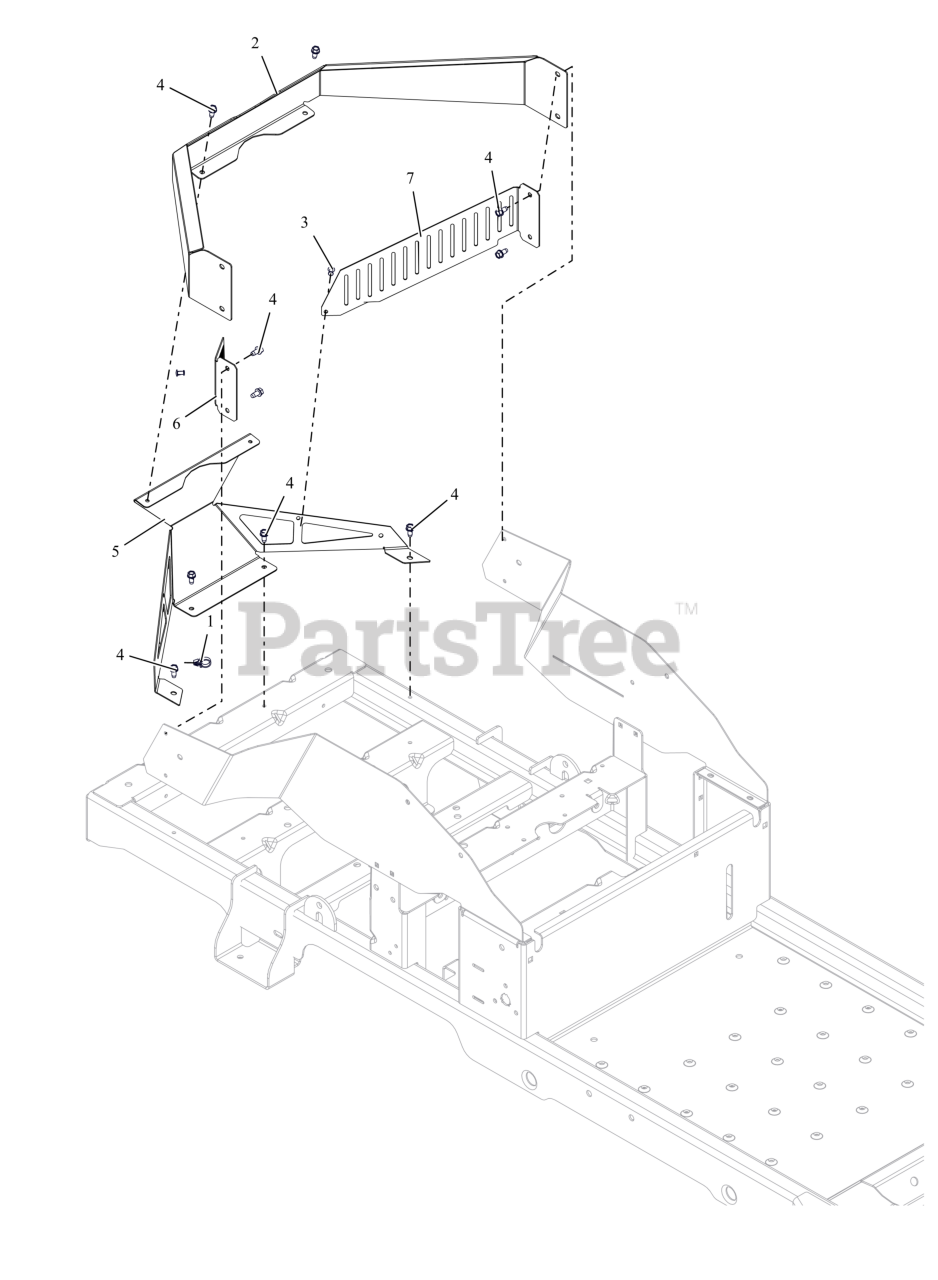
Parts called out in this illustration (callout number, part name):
1	ROUTING CLIP (1/2" ID)
2	WRAP, REAR -TOP
3	RVT .187X.575 DOME AL BLACK
4	SCR-TAP .25-20X.50 HWH ZCC
5	WRAP, REAR EDGE CE (BLACK)
6	SHIELD, LH ENGINE GUARD EDGE CE (BLACK)
7	SHIELD, RH ENGINE GUARD EDGE CE (BLACK)
